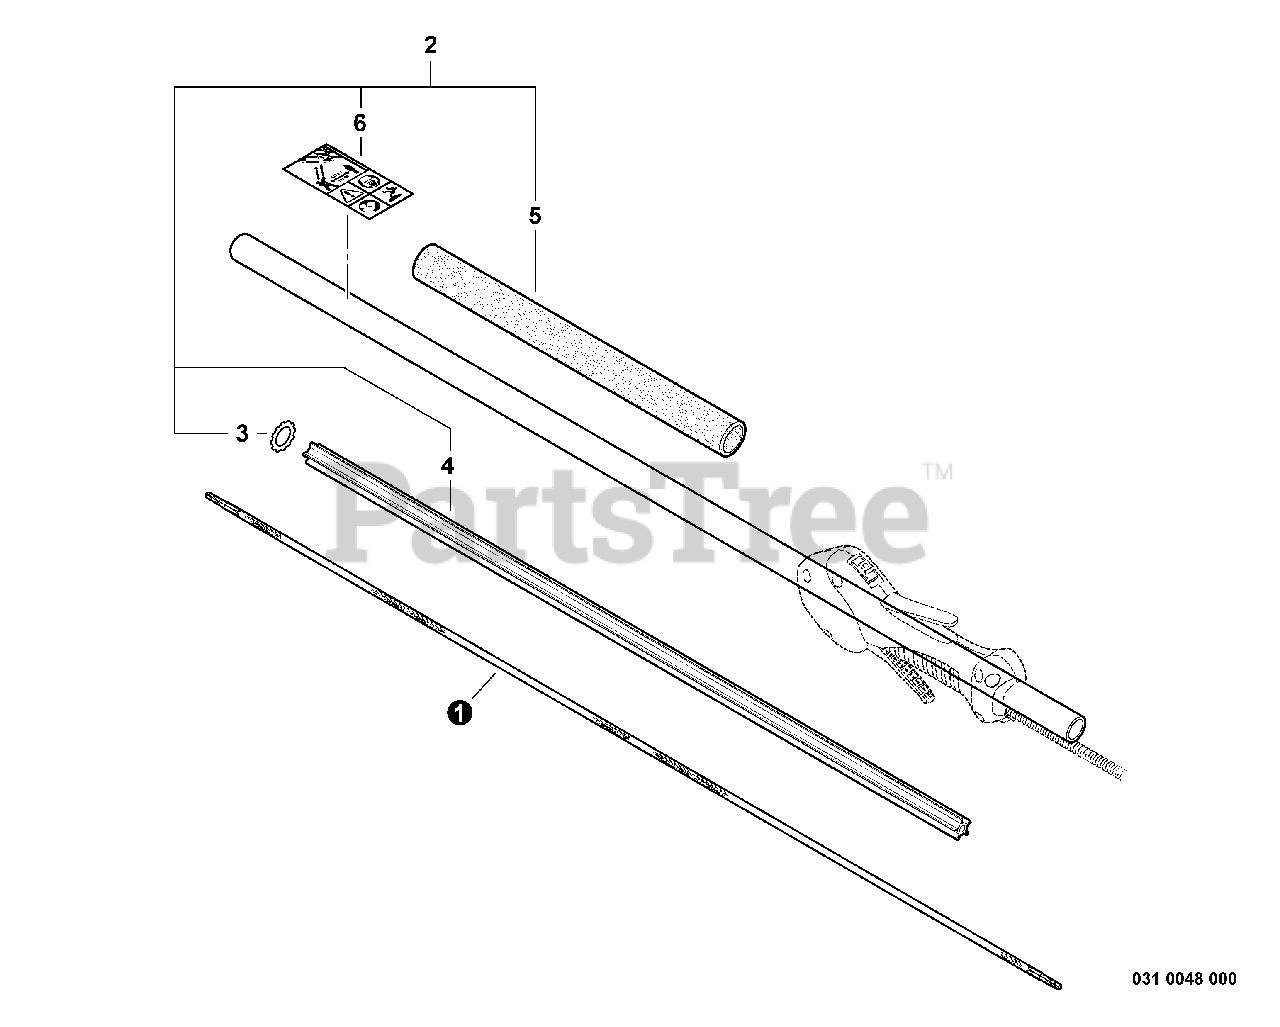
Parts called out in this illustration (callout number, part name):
1	DRIVESHAFT - FLEXIBLE
2	MAIN PIPE ASSY
3	LOCKWASHER - EXTERNAL
4	LINER - FLEXIBLE
5	GRIP, HANDLE - FRONT
6	LABEL - CAUTION
